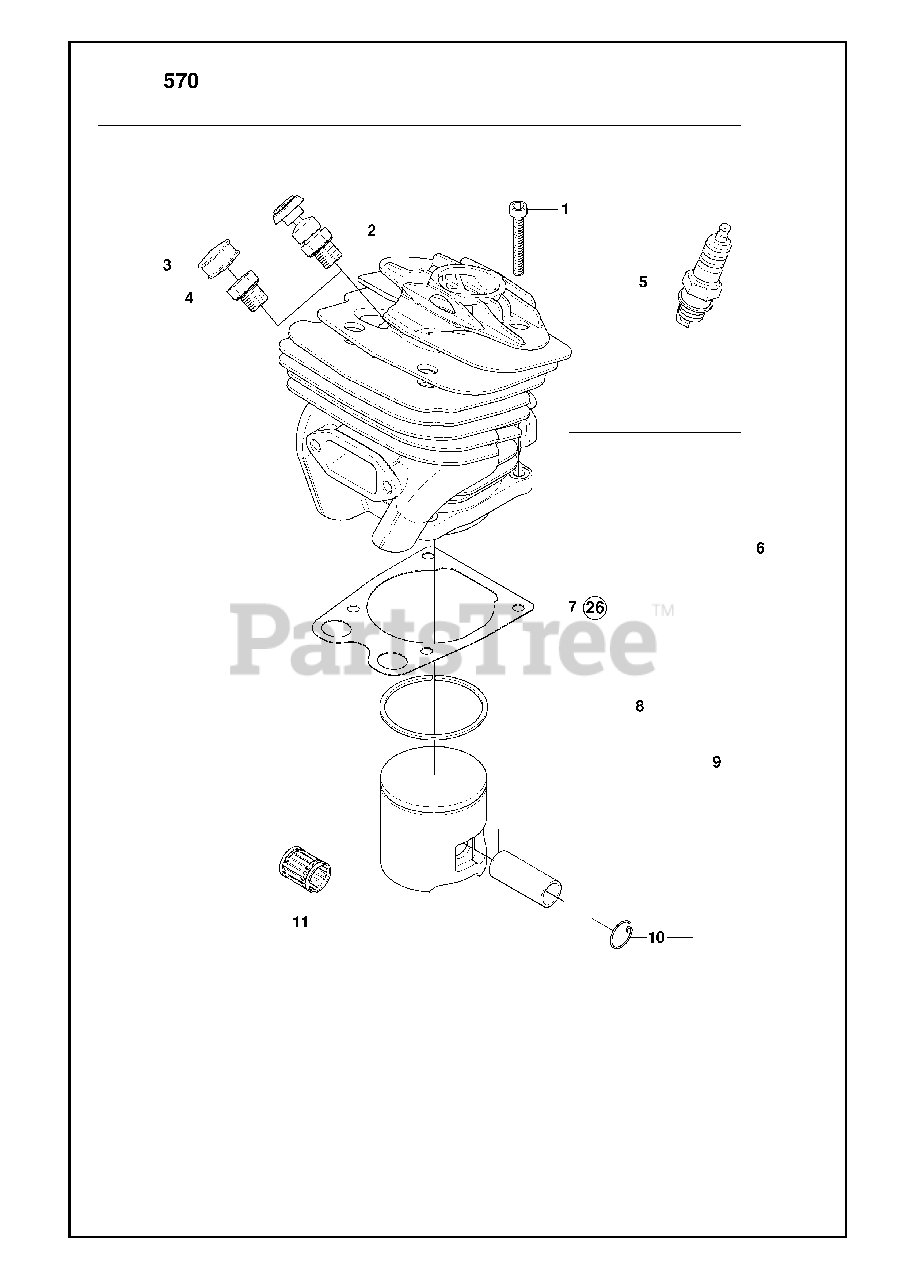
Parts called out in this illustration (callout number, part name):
1	SCREW MC6S 5X25
2	VALVE
4	CYLINDER PLUG
5	BPMR7A NGK SPARK PLUG
6	%CYLINDER
8	PISTON RING
9	PISTON 49 MM
10	WRIST PIN CLIP
11	SUPPORT BUSHING
26	GASKET SET
